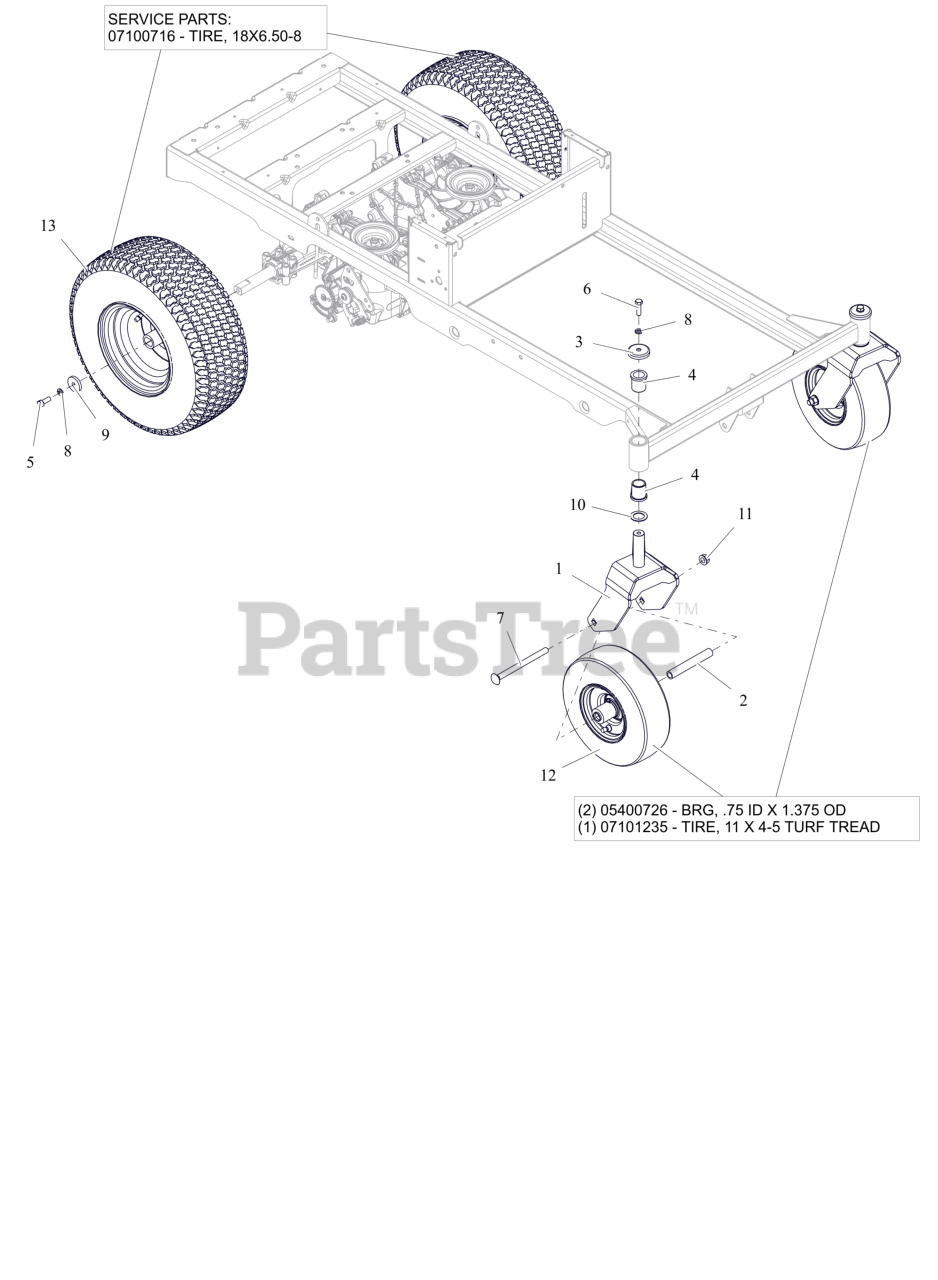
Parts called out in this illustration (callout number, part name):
1	WLDMT, CASTER FORK-X (ORANGE)
2	SPACER, ROLLED WHEEL
3	SHIELD, AXLE BEARING
4	BSHG-FLG 1.00X1.25X1.50X1.50
5	BLT, HEX .38-16X1.00 G8ZCCEP30
6	BLT, HEX .38-16X1.25 G5 ZCC
7	BLT, RHSN .50-13X6.50 G5 ZCC
8	WSHR,LK-REG .375X.094 ZCC
9	WSHR, FLT .406X1.50X.245 ZCC
10	WSHR-HRD-THRS 1.007X1.542X.062
11	NUT-LK-CTR-FLG .500-13 GG ZCC
12	ASM, WHL/TIRE 11X4.00-5
12	BRG, .75 ID X 1.375 OD
12	TIRE, 11X4-5 TURF TREAD
13	ASM, WHL/TIRE 18X6.50-8 DHUB
13	TIRE, 18X6.5-8
